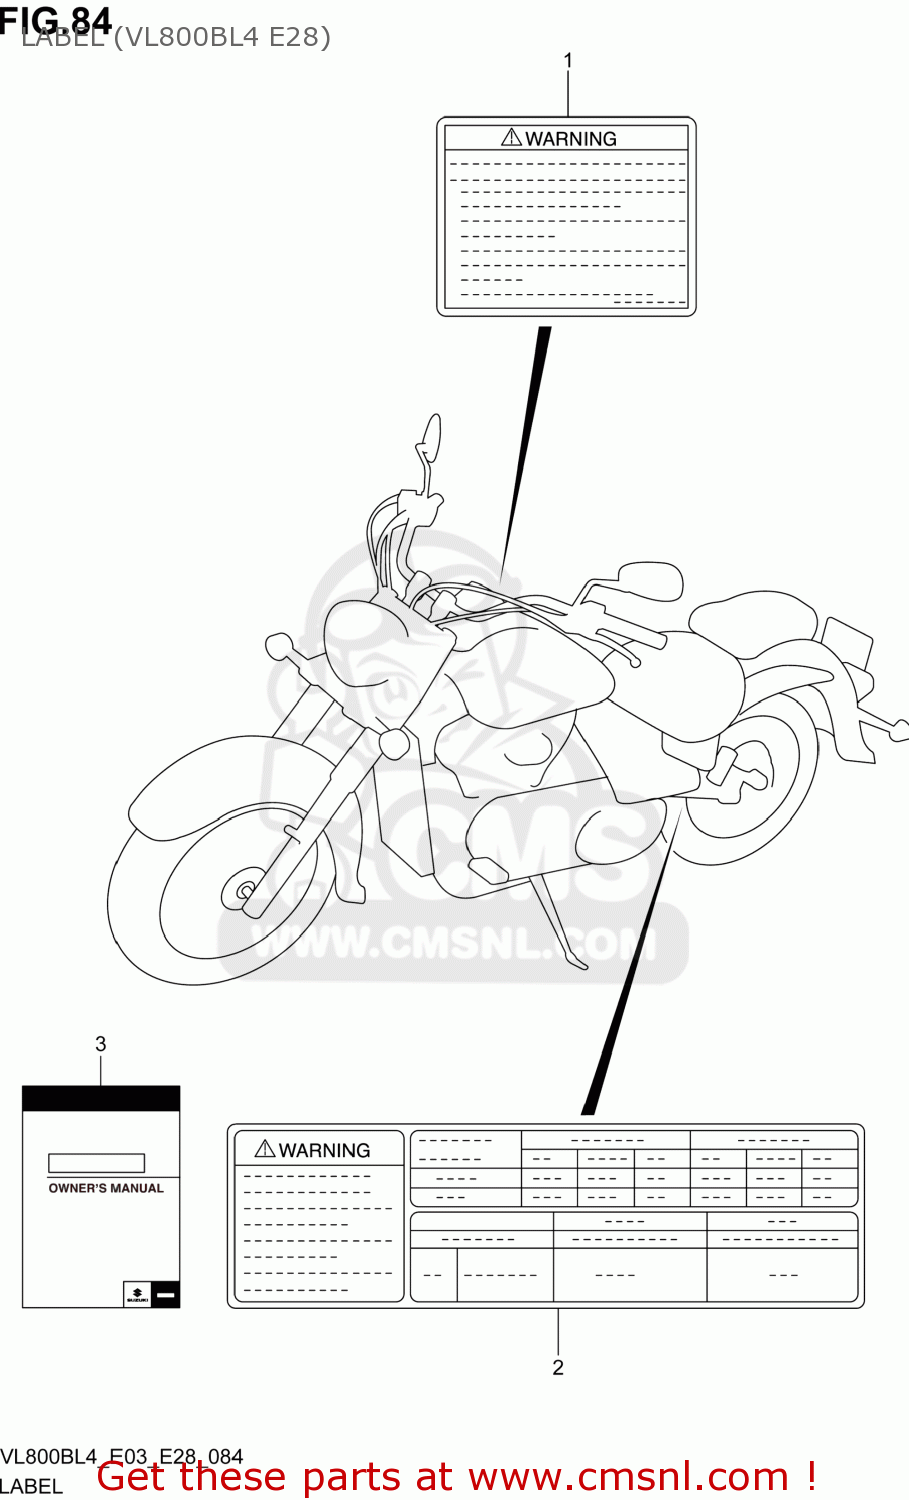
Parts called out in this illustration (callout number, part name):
1	LABEL,GENERAL WARNING
2	LABEL,TIRE INFORMATION
3	MANUAL,OWNER'S
